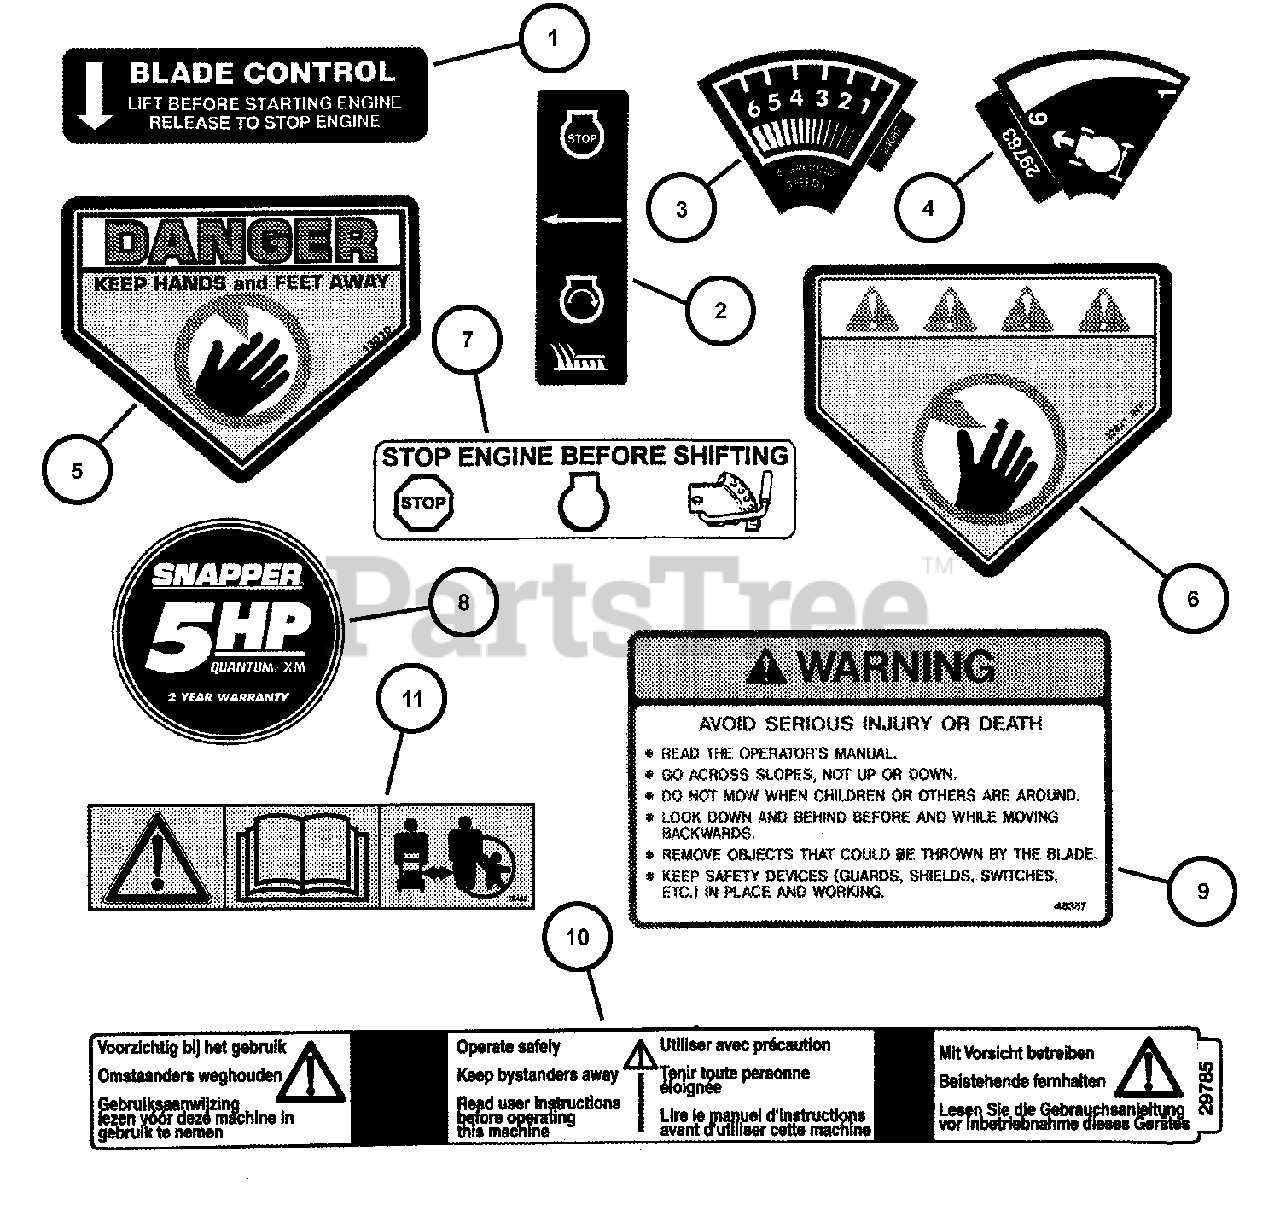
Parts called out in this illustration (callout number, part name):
1	DECAL, Blade Control
2	DECAL, Blade Control (Euro)
3	DECAL, Speed Select
4	DECAL, Speed Select (Euro)
5	DECAL, Danger, Cut Finger
6	DECAL, Warning (Euro)
7	DECAL, Shift Warning
8	DECAL, SNAPPER, 3.87 Dia. (Push)
9	DECAL, Warning
10	DECAL, Operator Safety
11	DECAL, Caution Symbols
